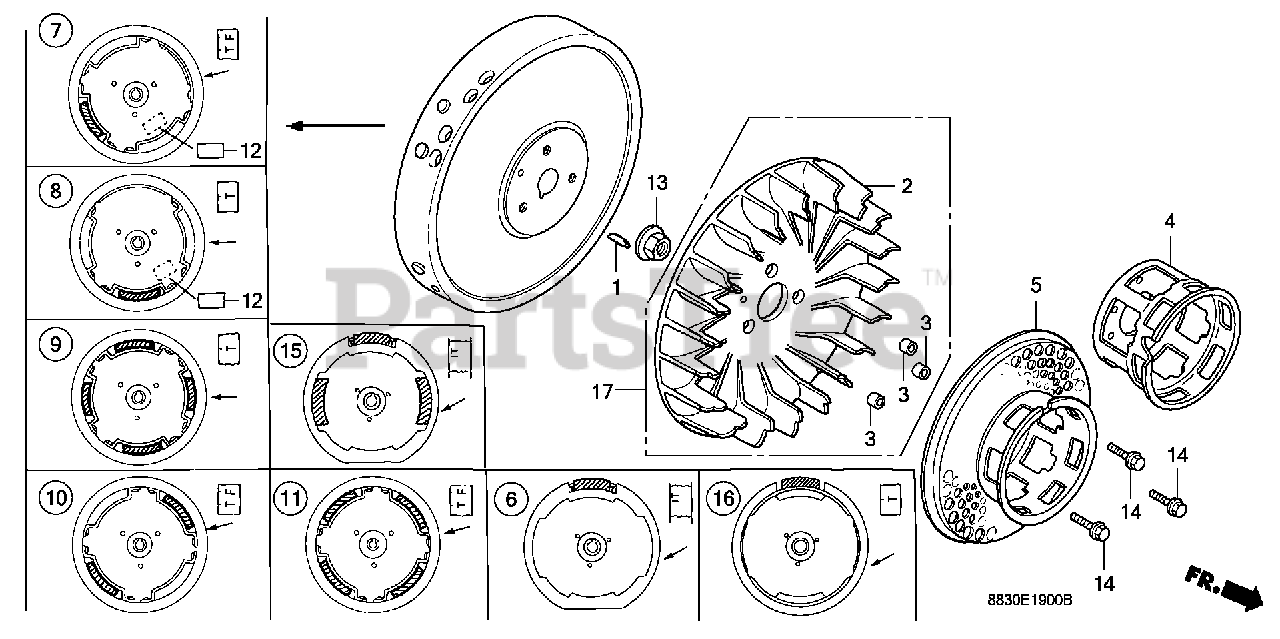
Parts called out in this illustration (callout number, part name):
1	KEY, SPECIAL WOODRUFF (25X18)
2	FAN, COOLING
3	COLLAR, FAN
5	PULLEY, STARTER
7	FLYWHEEL (POINT)
13	NUT, SPECIAL (14MM)
14	BOLT, FLANGE (6X16)
